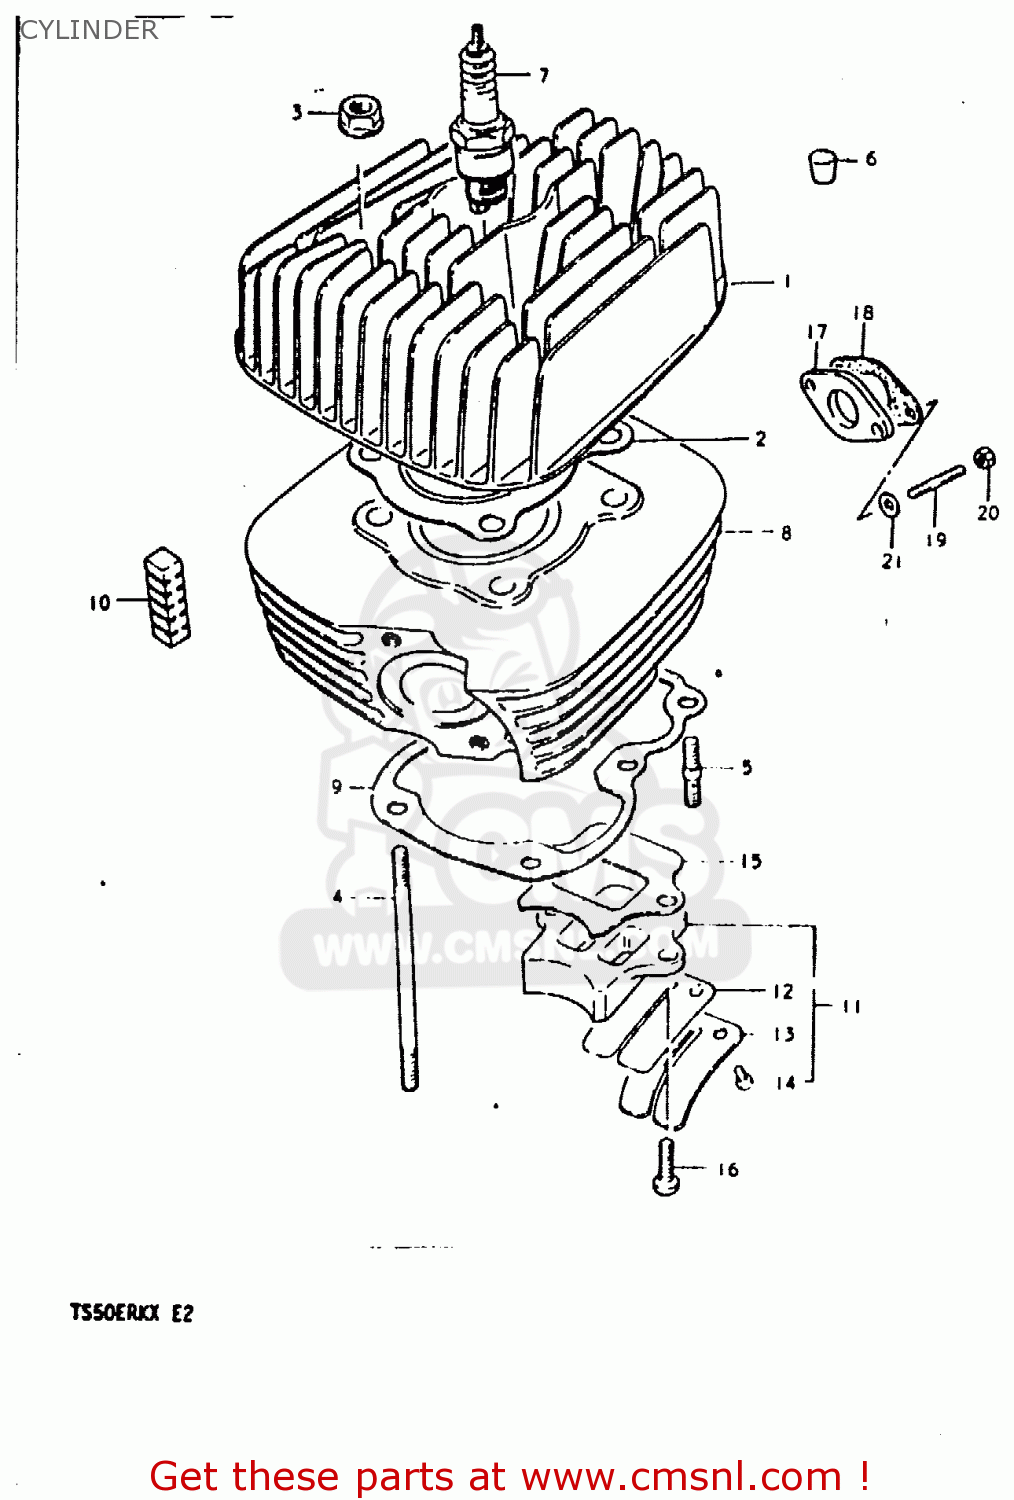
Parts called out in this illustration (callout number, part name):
1	CYLINDER HEAD
2	GASKET,CYLINDER HEAD (NAS)
3	NUT
4	BOLT,STUD
5	STUD 6X16
7	SPARK PLUG (ND,W20EP)
8	CYLINDER
9	GASKET,CYLINDER (MCA)
10	PAD,CYLINDER
17	INSULATOR,CARBURETOR
18	GASKET,CARBURETOR (MCA)
19	STUD BOLT
20	NUT
21	WASHER
